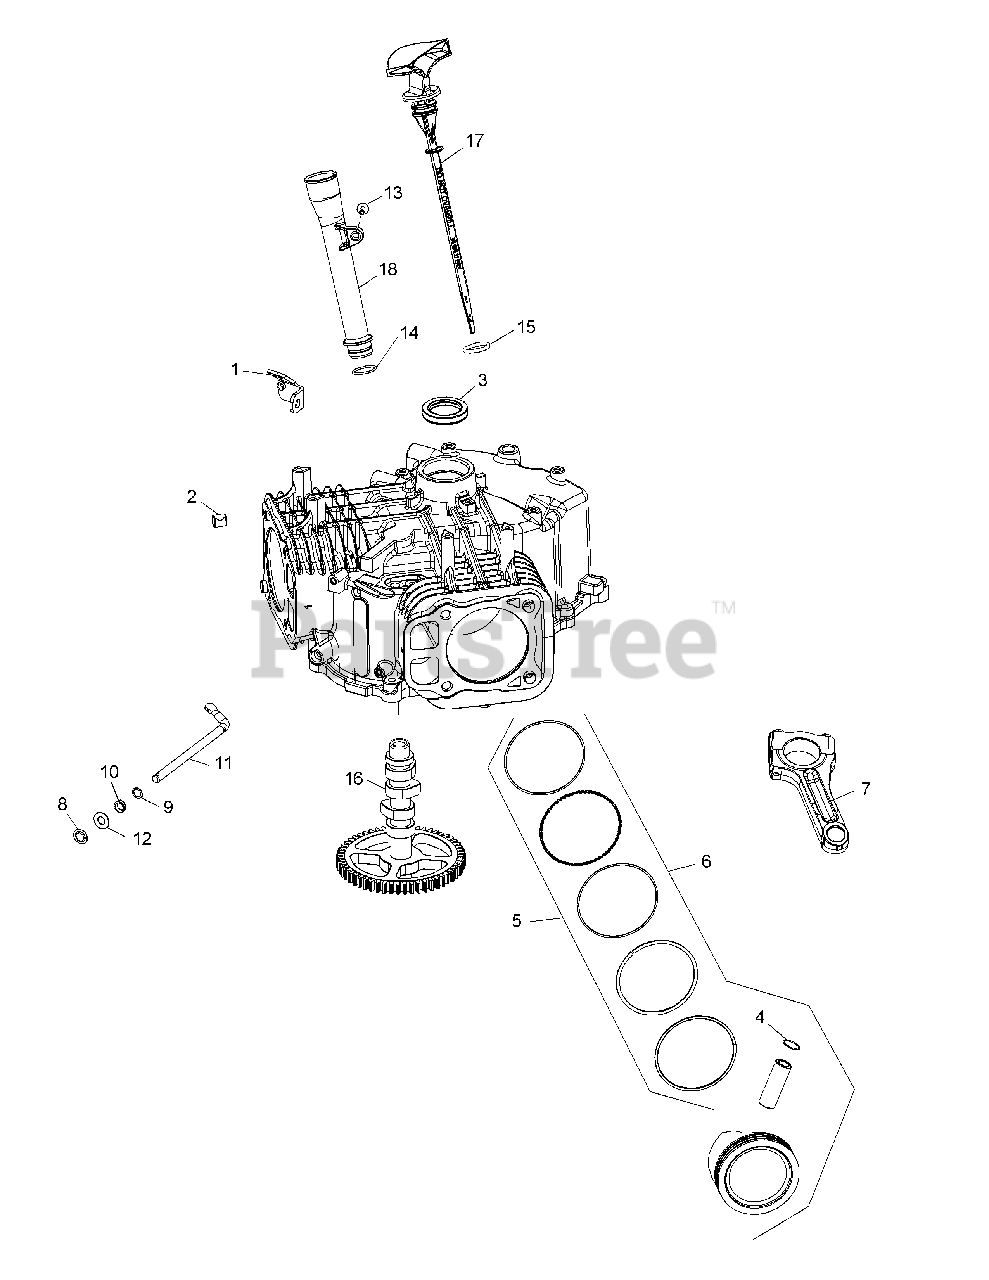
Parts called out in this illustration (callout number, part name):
1	Oil Fill Tube Bracket
3	Oil Seal, 1.78 x 1.26
4	Piston Pin Retainer
5	Piston Ring Set (STD)
5	Piston Ring Set (.08)
5	Piston Ring Set (.25)
5	Piston Ring Set (.50)
6	Piston Kit w/ Ring (STD) (Inc. 4 & 5)
6	Piston Kit w/ Ring (.08)
6	Piston Kit w/ Ring (.25)
6	Piston Kit w/ Ring (.50)
7	Connecting Rod (STD)
7	Connecting Rod (U/S .010) (25mm)
8	Ring Retainer
9	Flat Washer, 11/32"
10	Governor Cross Shaft Seal
11	Governor Cross Shaft
12	Flat Washer, 9 mm
13	Thread Forming Screw
14	O-Ring
16	Camshaft Assembly
17	Dipstick Assembly
18	Oil Fill Tube Assembly
